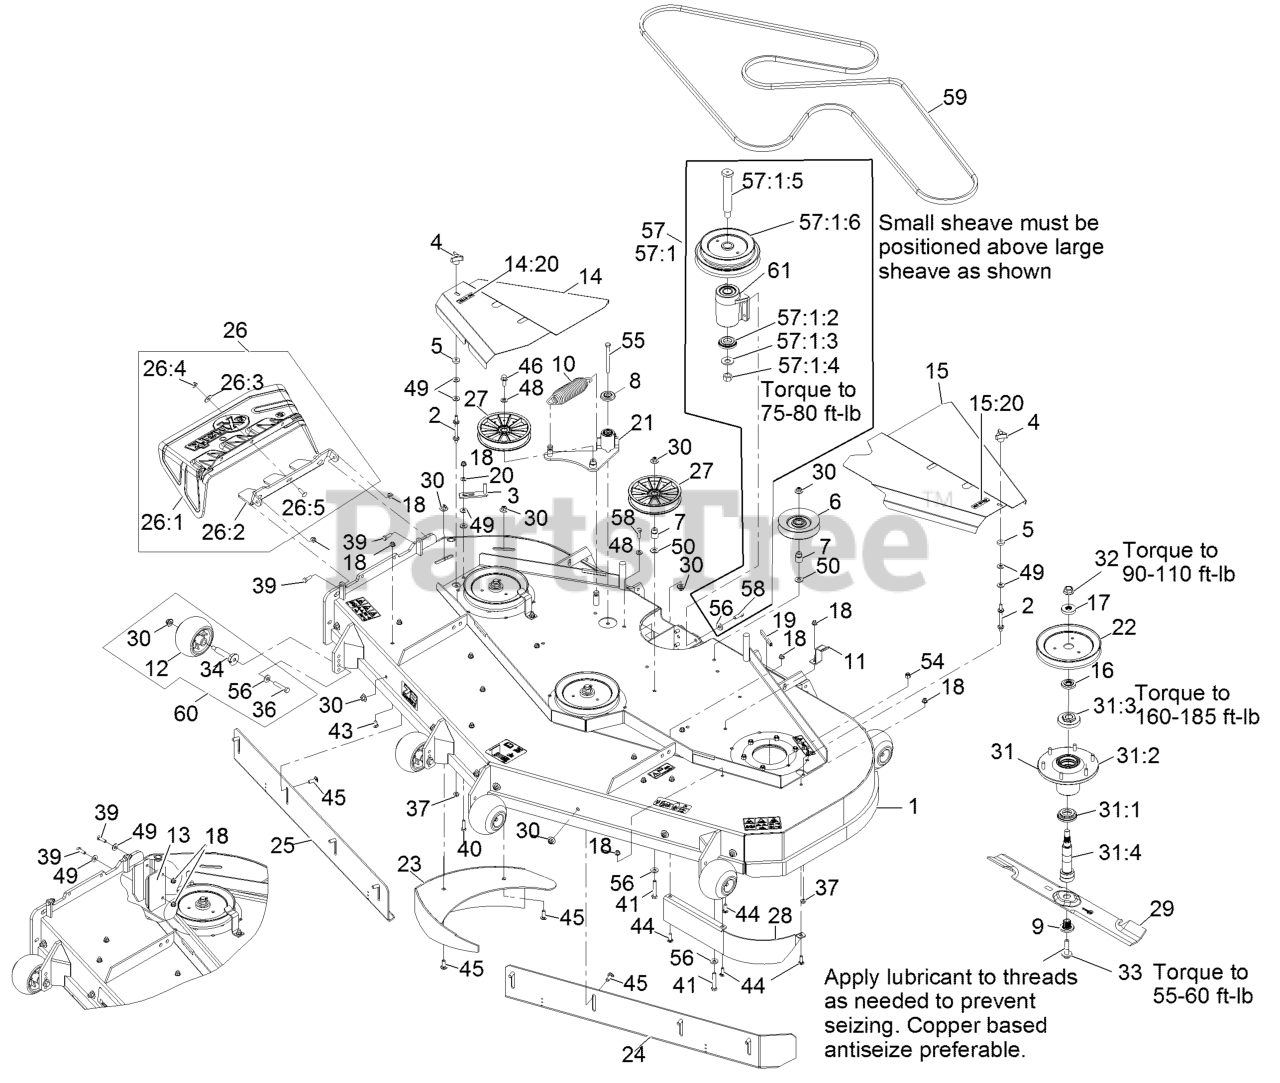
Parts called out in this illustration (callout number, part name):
1	ASM, DECK 725 W/DECALS
2	STUD-SHIELD, BELT (SHORT)
3	GUIDE-BELT
4	KNOB-3 PRONG
6	PULLEY-IDLER
7	BUSHING-IDLER
8	GUARD-TOP
9	BUSHING,SPLINED
10	SPRING-EXTENSION
11	LATCH,BELT SHIELD
12	ROLLER-SCALP, ANTI
13	DEFLECTOR,DISCHARGE
14	SHIELD, BELT RH 725 W/DEC
14:20	DECAL,NO STEP
15	SHIELD,BELT LH 725 W/DECA
15:20	DECAL,NO STEP
16	SPACER,SPLINED STEPPED
17	SPACER,SPLINED
18	NUT-HF, NI
19	STRIP-SEAL
20	WASHER-SPRING
21	KIT, IDLER ARM W/BEARINGS
22	SHEAVE,BLADE DRIVE 7.25
23	WLD,DOGLEG 725
24	WLD,BAFFLE FRT ADJ LH 725
25	WLD,BAFFLE FRT ADJ RH 725
26	ASM, DISCHARGE CHUTE
26:1	CHUTE,DISCHARGE LZ
26:2	HINGE,DISCHARGE CHUTE
26:3	WASHER-FLAT
26:4	NUT-HF, NI
26:5	SCREW-CARR
27	PULLEY,IDLER 6"
28	BAFFLE,SCROLL 725
30	Nut-Nyloc 3/8-16 Flg
31	ASM,SPINDLE HOUSING
31:1	GUARD,BOTTOM
31:2	ASM,CUTTER HOUSING
31:3	NUT, SPINDLE 7/8-14
31:4	SPINDLE,DOUBLE SPLINE
32	NUT-FLANGE, CENTERLOCK
33	SCREW,SEMS 1/2-20 X 2.19
34	AXLE, ROLLER
36	SCREW-HH 3/8-16 X 3 3/4 GR 8
39	SCREW-HH
40	SCREW-HH
41	SCREW-HH
43	SCREW-CARR
44	SCREW-CARR
45	SCREW-CARR
46	SCREW-HHF
48	WASHER-FLAT
49	WASHER-FLAT
50	WASHER-FLAT
54	NUT-LOCK, NI
55	SCREW-HH
56	WASHER-BELLEVILLE
57	KIT,JACKSHAFT 60/72-3750
57:1:2	SPACER-GUARD, BOTTOM
57:1:3	WASHER-SPRING
57:1:4	NUT-HEX
57:1:5	JACKSHAFT
57:1:6	SHEAVE, JACKSHAFT DOUBLE
58	SCREW-HH
59	BELT-V
60	KIT, ANTI-SCALP ROLLER
61	KIT, JACKSHAFT ASSY
